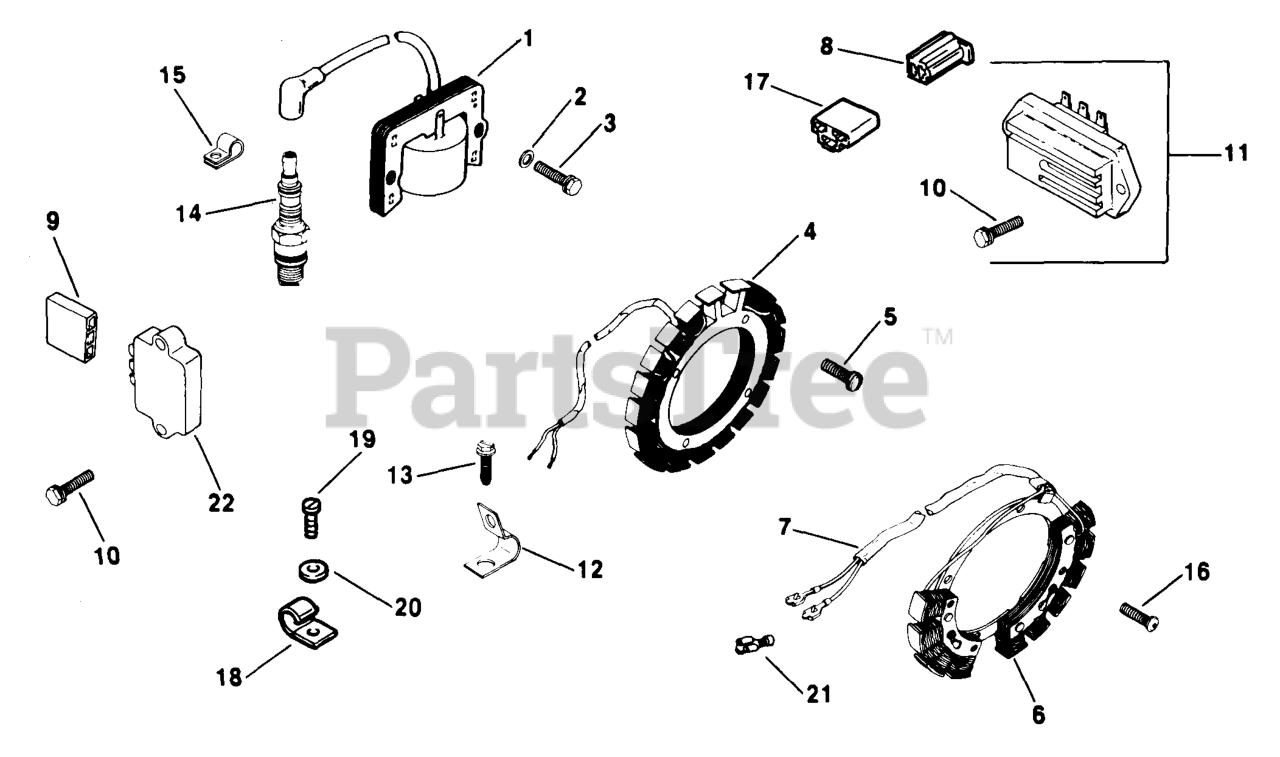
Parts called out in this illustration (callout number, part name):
1	MODULE - USE 47 584 02
2	WASHER, FLAT 3/16"
3	SCREW - USE X-67-51-S
14	SPARK PLUG USE 25 132 10-S
